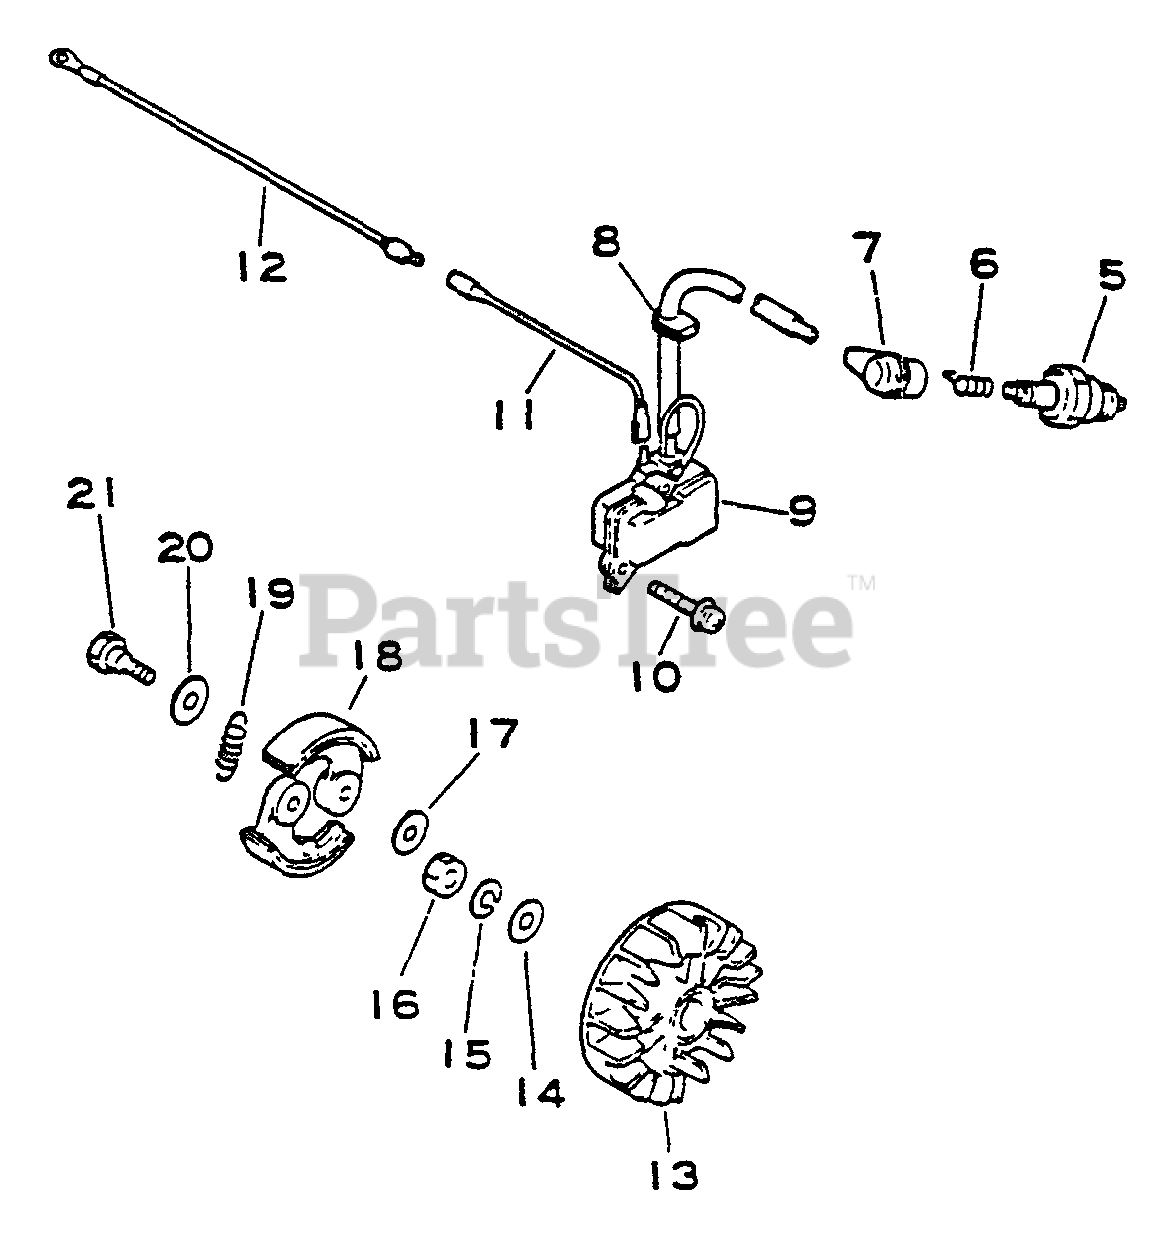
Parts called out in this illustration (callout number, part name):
5	SPARK PLUG -- BPM-7A
6	TERMINAL, SPARK PLUG CAP
7	CAP, SPARK PLUG
9	COIL, IGNITION
10	SCREW - 5X20
11	LEAD - IGNITION
12	LEAD - GROUND
13	FLYWHEEL
14	WASHER - 10
15	LOCKWASHER - 10
16	NUT - 10
18	SHOE, CLUTCH
19	SPRING, CLUTCH
21	BOLT, CLUTCH
